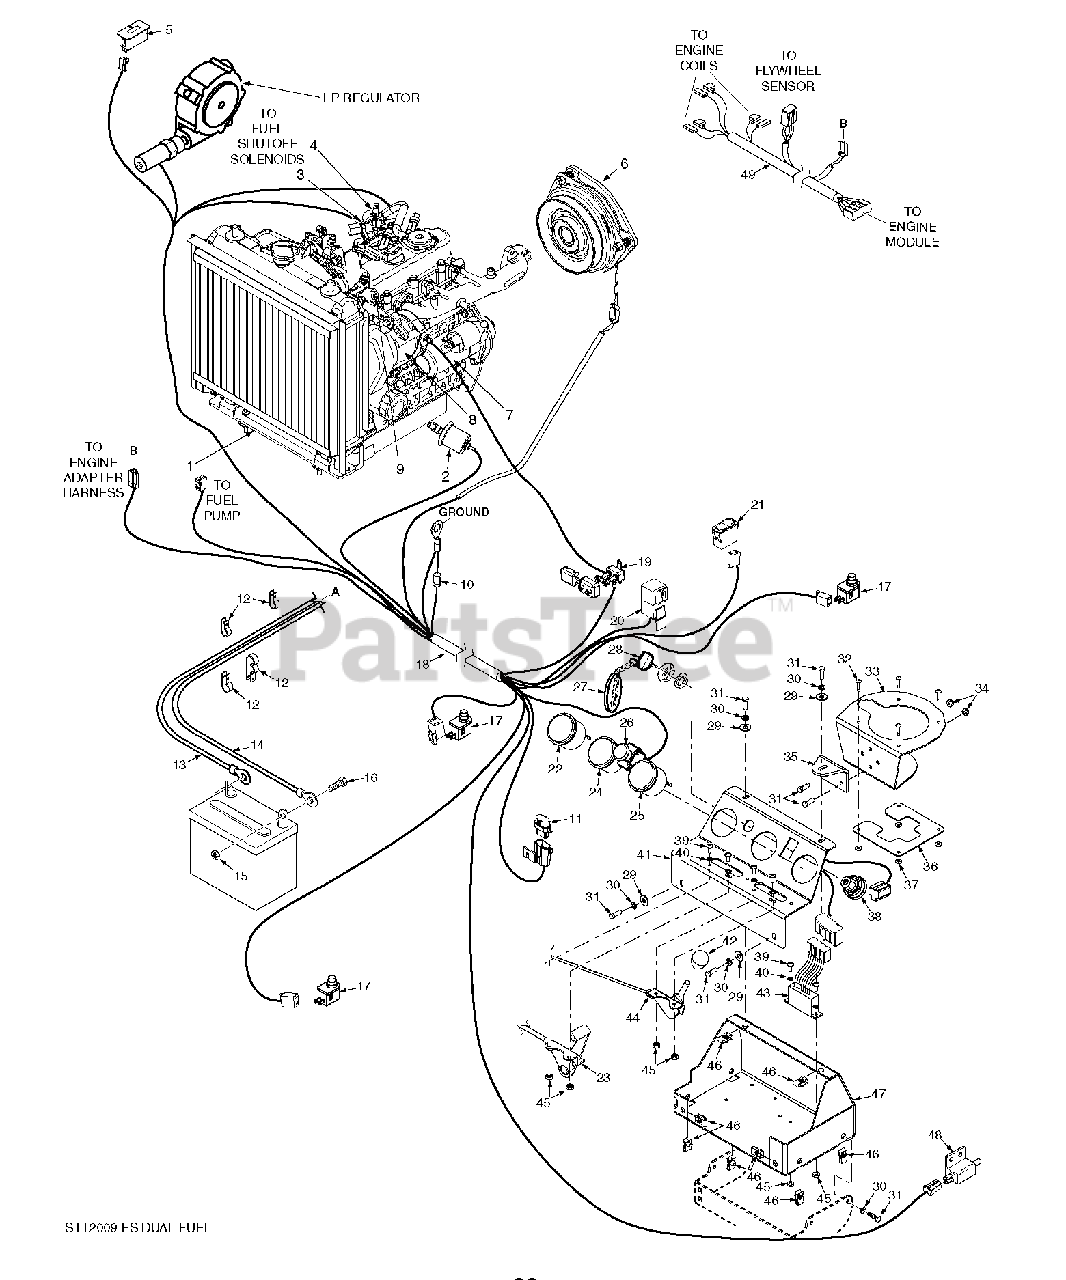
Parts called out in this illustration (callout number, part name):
1	Fuel Pump
2	Oil Pressure Sender
3	LP Shutoff Solenoid
4	Fuel Shutoff Solenoid
5	Hourmeter
6	Clutch, Ogura GT 3.5 - 1.125 Bore
7	Starting Motor
8	Alternator
9	Sending Unit, Water Temp.
10	Diode
11	Fuse, 20 AMP
12	Clamp, Cable 1/2" ID.
13	Cable, Battery - Red
14	Cable, Battery - Black
15	Nut, Hex 1/4-20
16	Bolt, Hex Head 1/4-20 x .5" Battery
17	Switch, Interlock, Normally Open
18	Main Wire Harness, STT Dual Fuel
19	Circuit Breaker, 50 AMP
20	Relay, 12V
21	Switch, Fuel Selector
22	Volt Meter
23	Indicator Light, Glow Plugs
24	Engine Oil Pressure Gauge
25	Water Temperature Gauge
26	Switch, PTO
27	Key Assembly w/Fob
28	Key, Ignition
29	Flat Washser, 1/4"
30	Lockwasher, 1/4"
31	Bolt, Hex Head 1/4-20 x 3/4"
32	Pop Rivet, 3/16" x 5/8"
33	Cupholder
34	Nut, Elastic Stop 1/4"-20
35	Bracket, Cupholder Mounting
36	Retainer, Cupholder
37	Flatwasher, 0.196 ID.
38	Key Switch
39	Screw, Phillips Washer Head #10-32 x 1/2"
40	Lockwasher, #10 External Tooth
41	Instrument Panel, Top w/Decals
42	Knob, Throttle
43	Electronic Control Module
44	Throttle Control
45	Nut, Hex #10-32
46	U-Nut, 1/4-20
47	Base, Instrument Panel
48	Switch, Interlock, Park Brake Normally Open
49	Wire Harness Adapter, Kubota Dual Fuel
